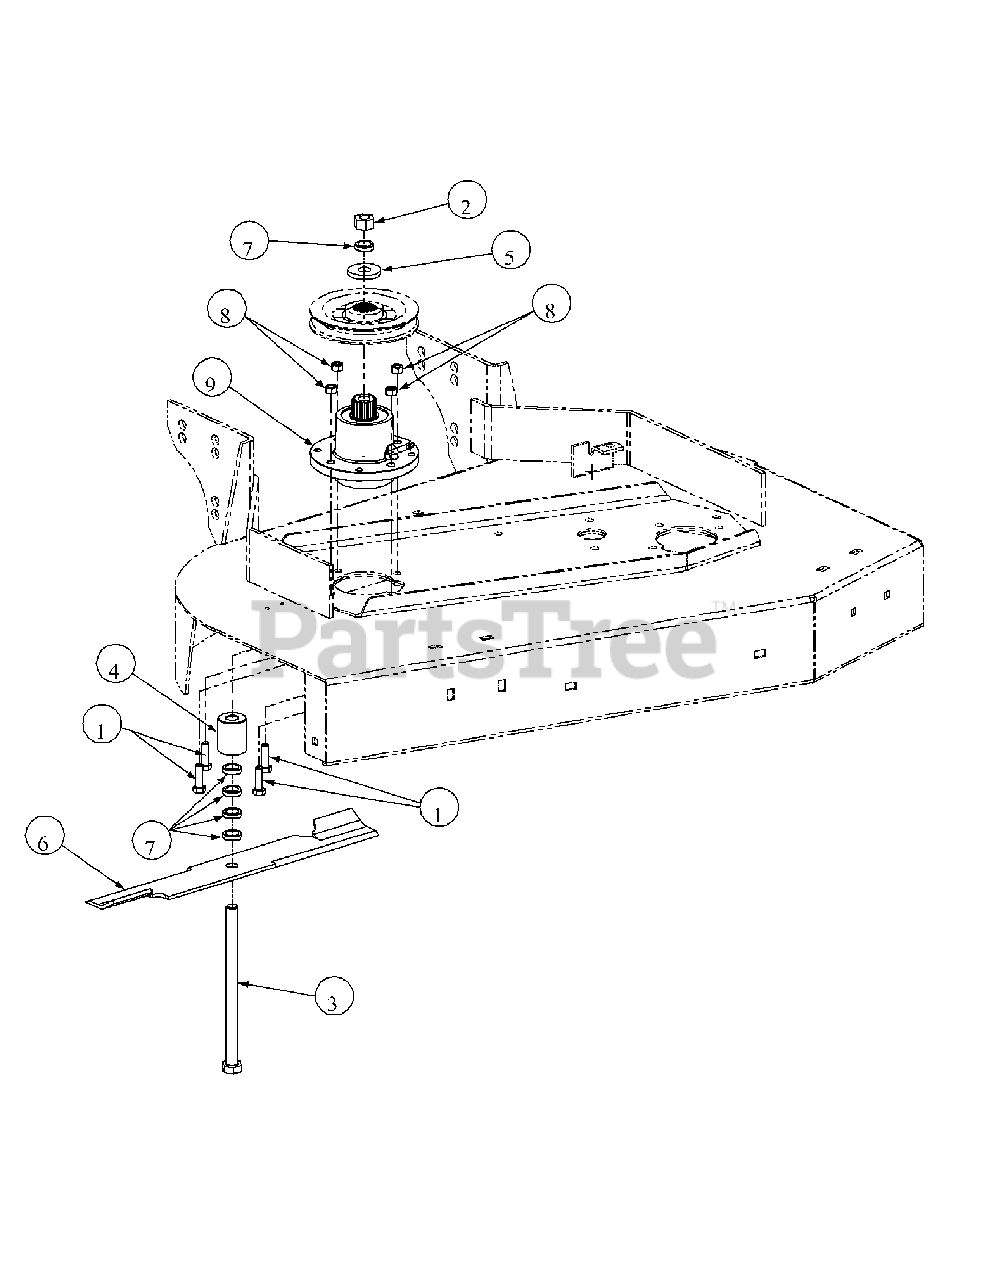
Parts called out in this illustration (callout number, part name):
1	Hex Cap Screw, 3/8-16 x 1-1/4
2	Hex Nut, 5/8-11
3	Hex Cap Screw, 5/8-11 x 9
4	Blade Spacer, .630 x 1.500 x 1.850
5	Flat Washer, .656 ID x 1.313 OD
6	16 1/2" Rotary Blade
7	Blade Spacer, 5/8 ID, 1/4 Thick
8	Lock Nut, 3/8-16
9	Spindle Assembly
